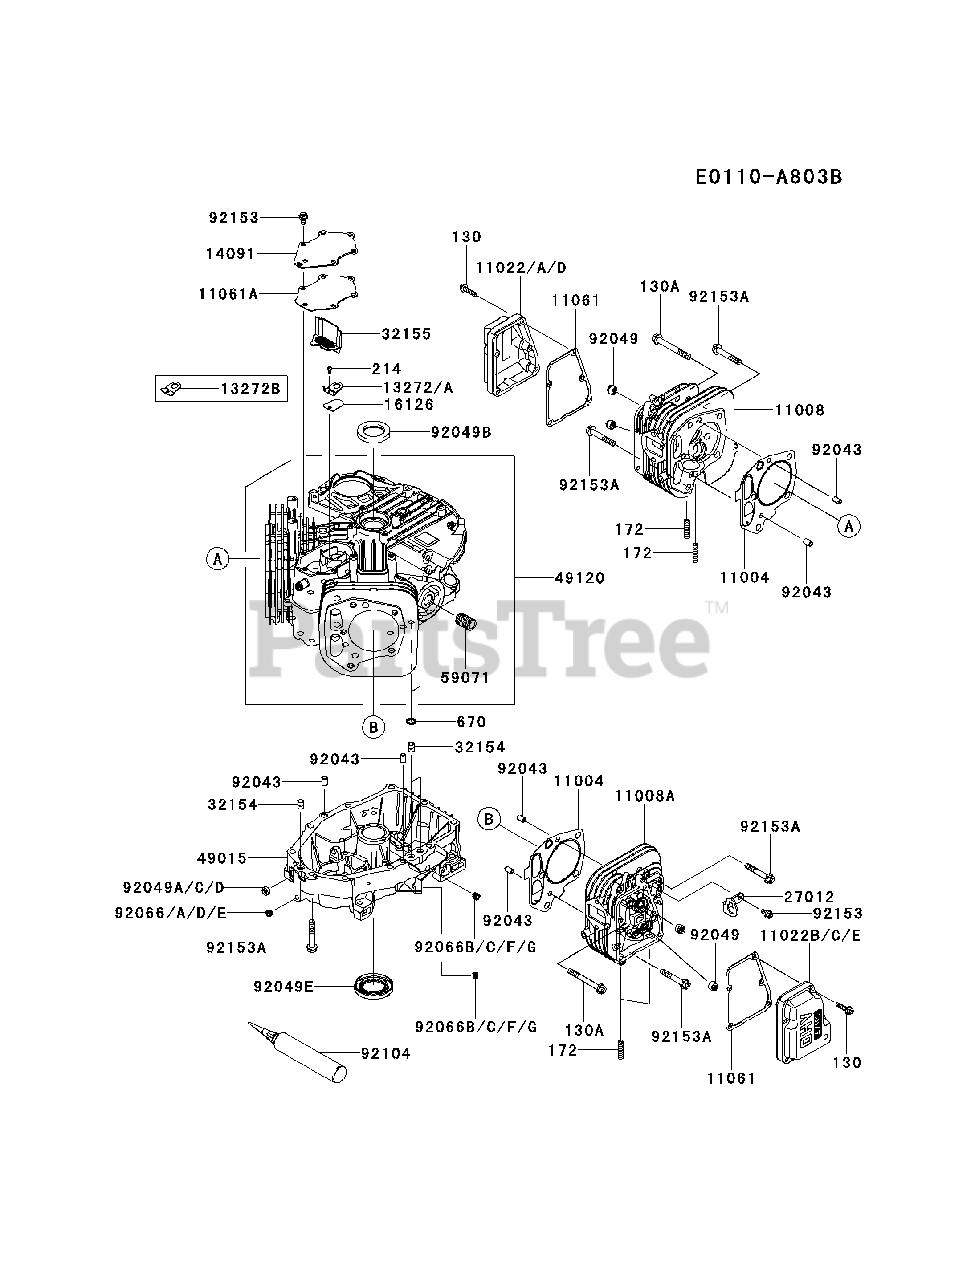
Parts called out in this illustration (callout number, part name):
130	BOLT-FLANGED,6X25
130A	BOLT-FLANGED,8X70
172	BOLT-STUD,8X18
214	SCREW-PAN+-,4X8
670	O RING,11MM
